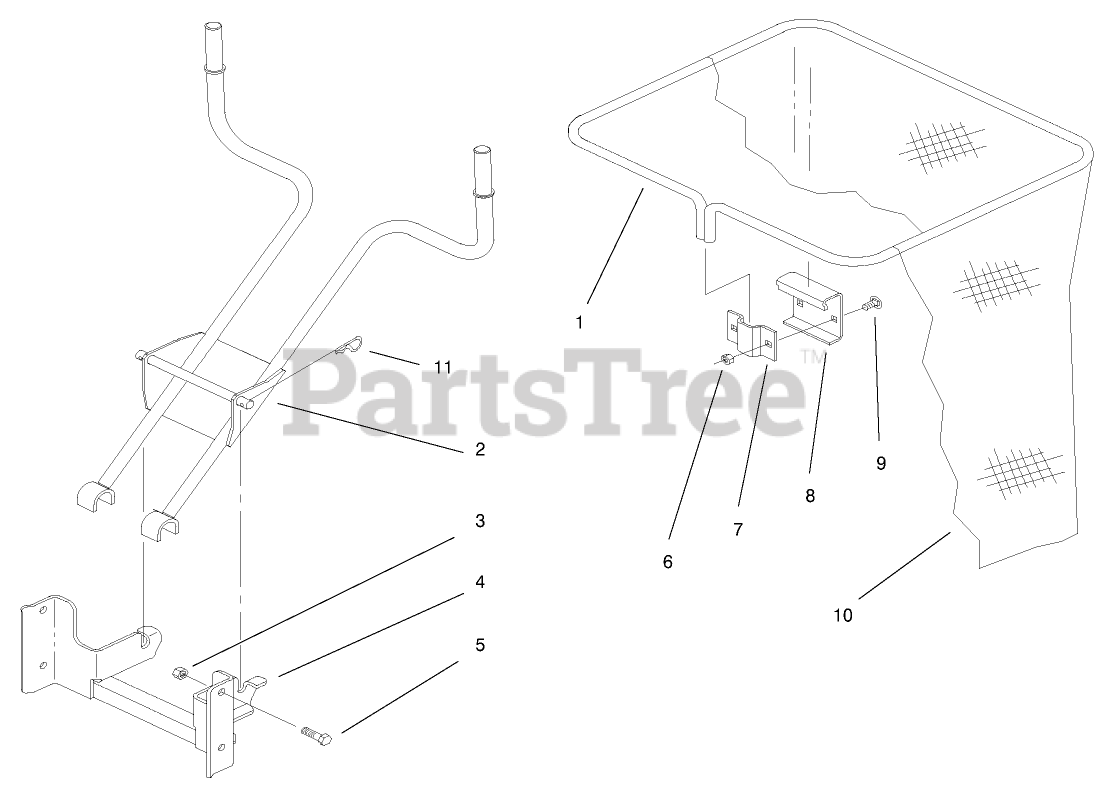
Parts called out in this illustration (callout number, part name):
1	FRAME-BAG
2	BRACKET-ATTACH, QUICK
3	NUT-LOCK, NI
4	SUPPORT-BAGGER
5	SCREW-HH
6	NUT-LOCK, NI
8	HANGER-BAG
9	BOLT-CARR
10	BAG-DEPTH
11	PIN-COTTER, HAIR
